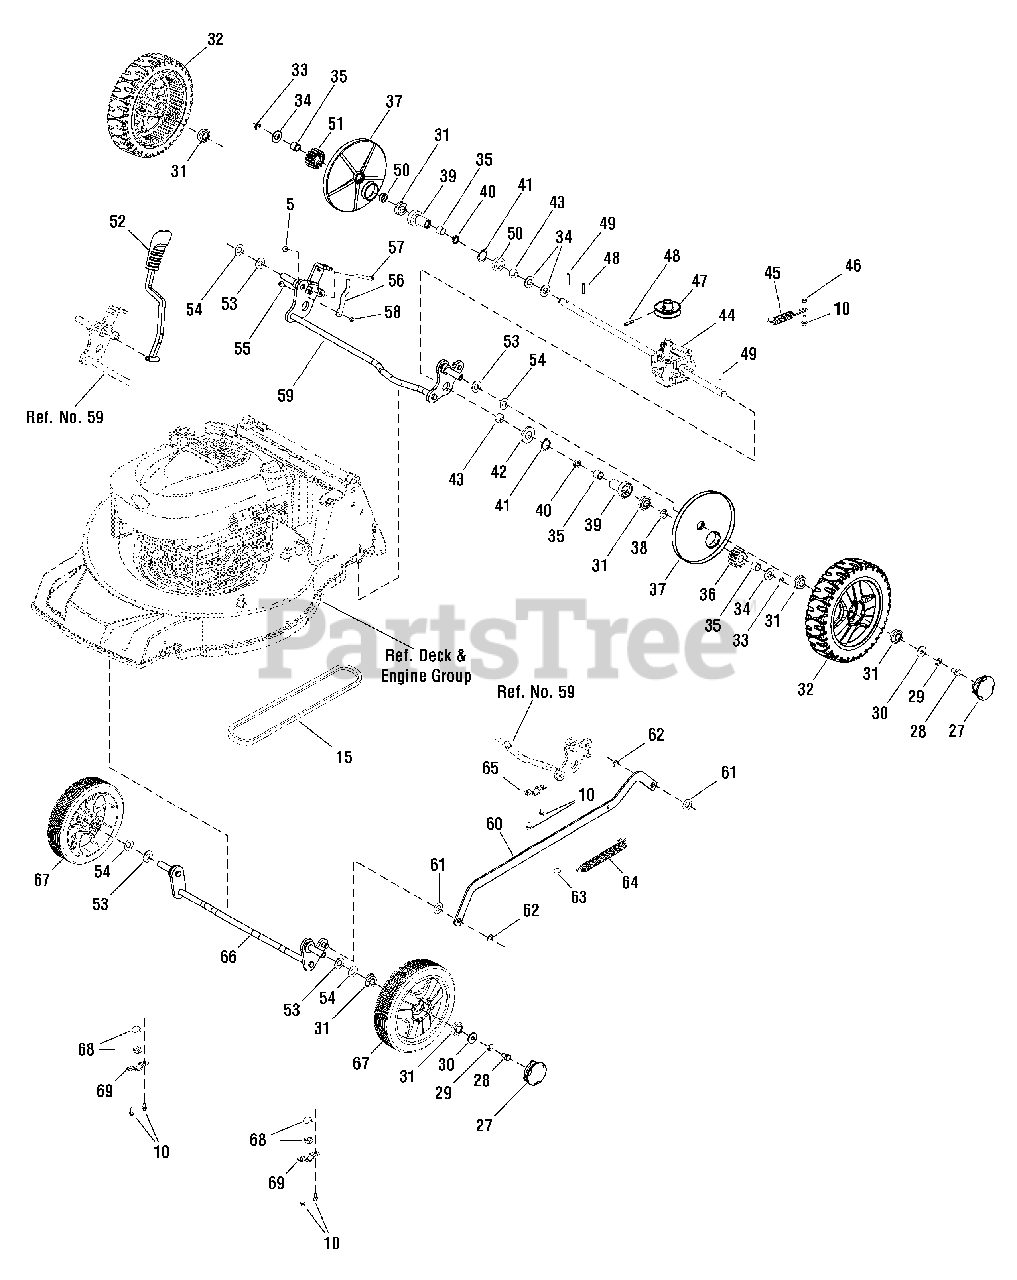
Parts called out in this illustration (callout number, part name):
5	NUT, Hex, Nylon Insert, Torque Type
10	SCREW, Hex Flange, Tapping
15	V BELT, V10 × 783
27	COVER, Wheel
28	BOLT, Hexangular, Full Thread
29	WASHER, Spring
30	WASHER, Flat, C-Class
31	BEARING
32	WHEEL, Rear, 8"
33	RING, Check
34	WASHER, Anti-friction
35	OIL BEARING B
36	PINION, Left
37	SHIELD, Dust, Rear
38	SPACER, Axle
39	BEARING SHEATH
40	RING, Dustproof
41	RING, Elastic, For A-form Axle
42	WASHER, Left Bearing Bracket
43	BALL BEARING, Nylon
44	TRANSMISSION, Single Speed
45	SPRING, Gearbox
46	WASHER, Spring
47	PULLEY, Gearbox
48	PIN, Elastic, Cylindrical
49	PIN, Sliding
50	SPACER, Transmission
51	PINION, Right
52	LEVER, Height Adjust
53	WASHER, Wheel Axle
54	SPACER, Spring
55	BOLT, Hexangular, Full Thread
56	SPRING, Armature
57	BOLT, Hexangular
58	NUT, Hex, Nylon Insert, Torque Type
59	AXLE, Rear
60	CONNECTING ROD
61	WASHER, Nylon
62	CHECK RING
63	CHECK CAP
64	SPRING, Connecting Rod
65	BRACKET, Upper Ball Bearing
66	AXLE, Front
67	WHEEL, Front, 8"
68	BALL BEARING
69	BRACKET, Front Ball Bearing
